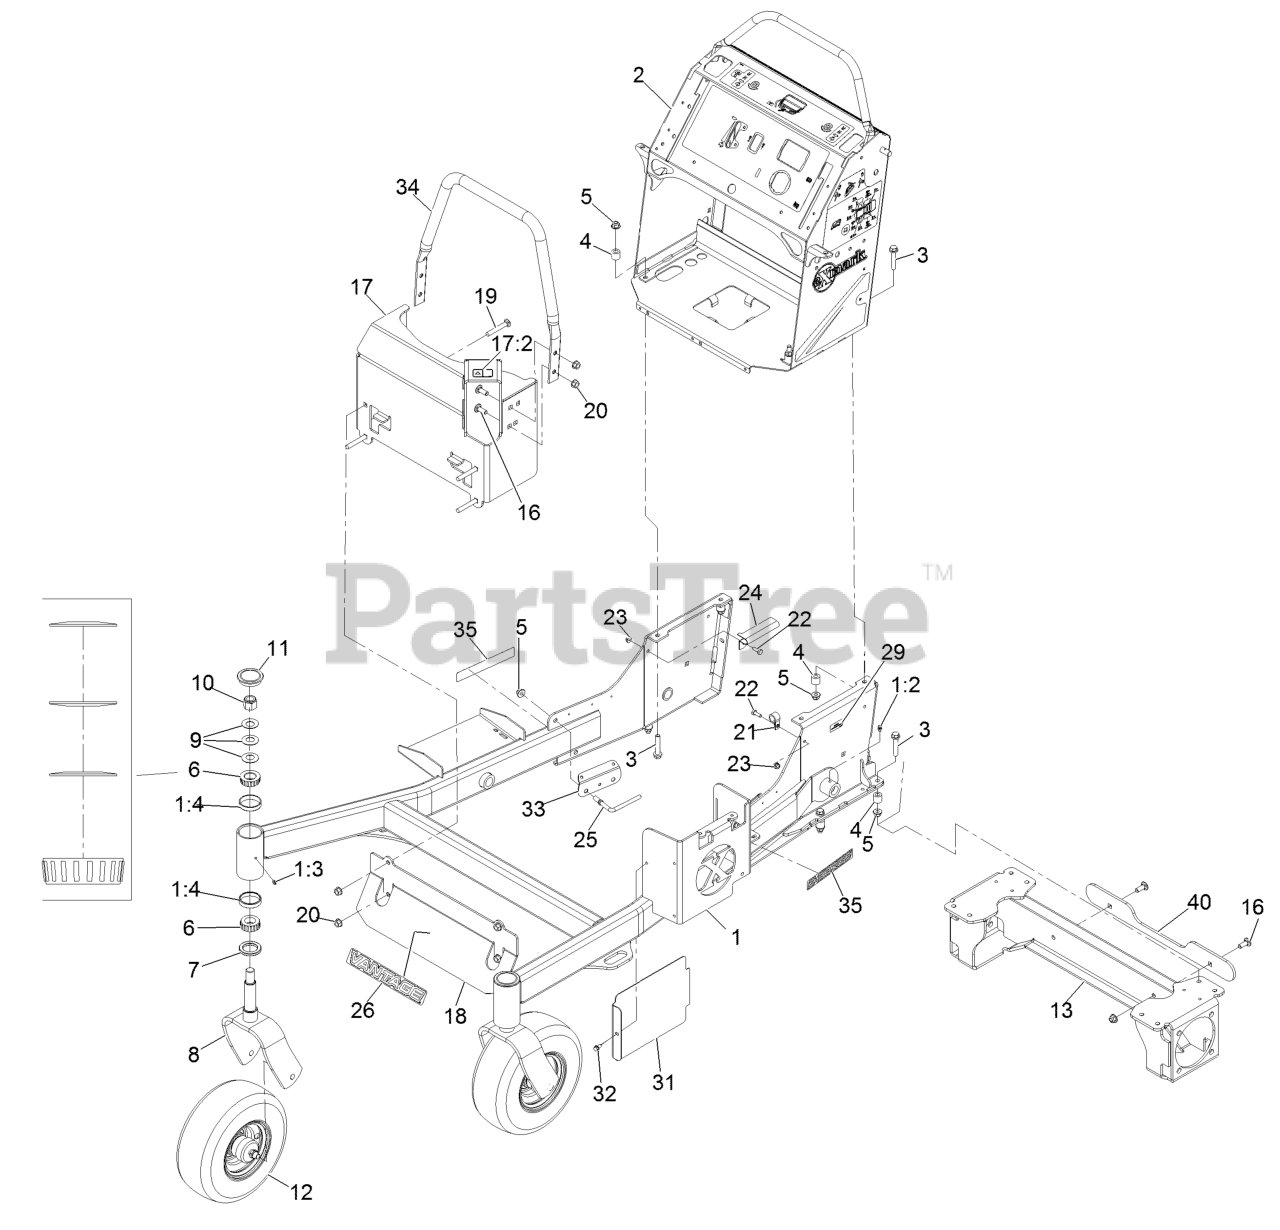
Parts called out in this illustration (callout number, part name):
1	FRONT FRAME ASM
1:2	FITTING-GREASE
1:4	CUP-BEARING
2	ASM-CONTROL TOWER
3	SCREW-HHF
5	NUT-HF, NI
6	Cone-Bearing Tapered Roller
7	SEAL-GREASE
8	FORK-CASTER
9	WASHER-BELLVILLE
10	NUT-LOCK, NI
11	CAP-GREASE
12	WHEEL/TIRE AND BEARING AS
13	WELD, MOTOR FRAME
16	SCREW-CARR
17	ASM, MUFFLER GUARD W/ DEC
17:2	DECAL-WARNING
18	PANEL-GUARD
19	SCREW-CARR
21	CLAMP-CABLE
22	SCREW-HH
24	BRACKET-HOSE, FUEL
25	GUIDE-HOSE, SUPPORT
26	DECAL-VANTAGE LOGO
29	Decal-Patent
31	SHIELD-HEAT, TALL
32	SCREW-HWH
33	GUARD-HOSE
34	TUBE-GUARD
35	DECAL-S-SERIES
40	PLATE, BUMPER SPACER
